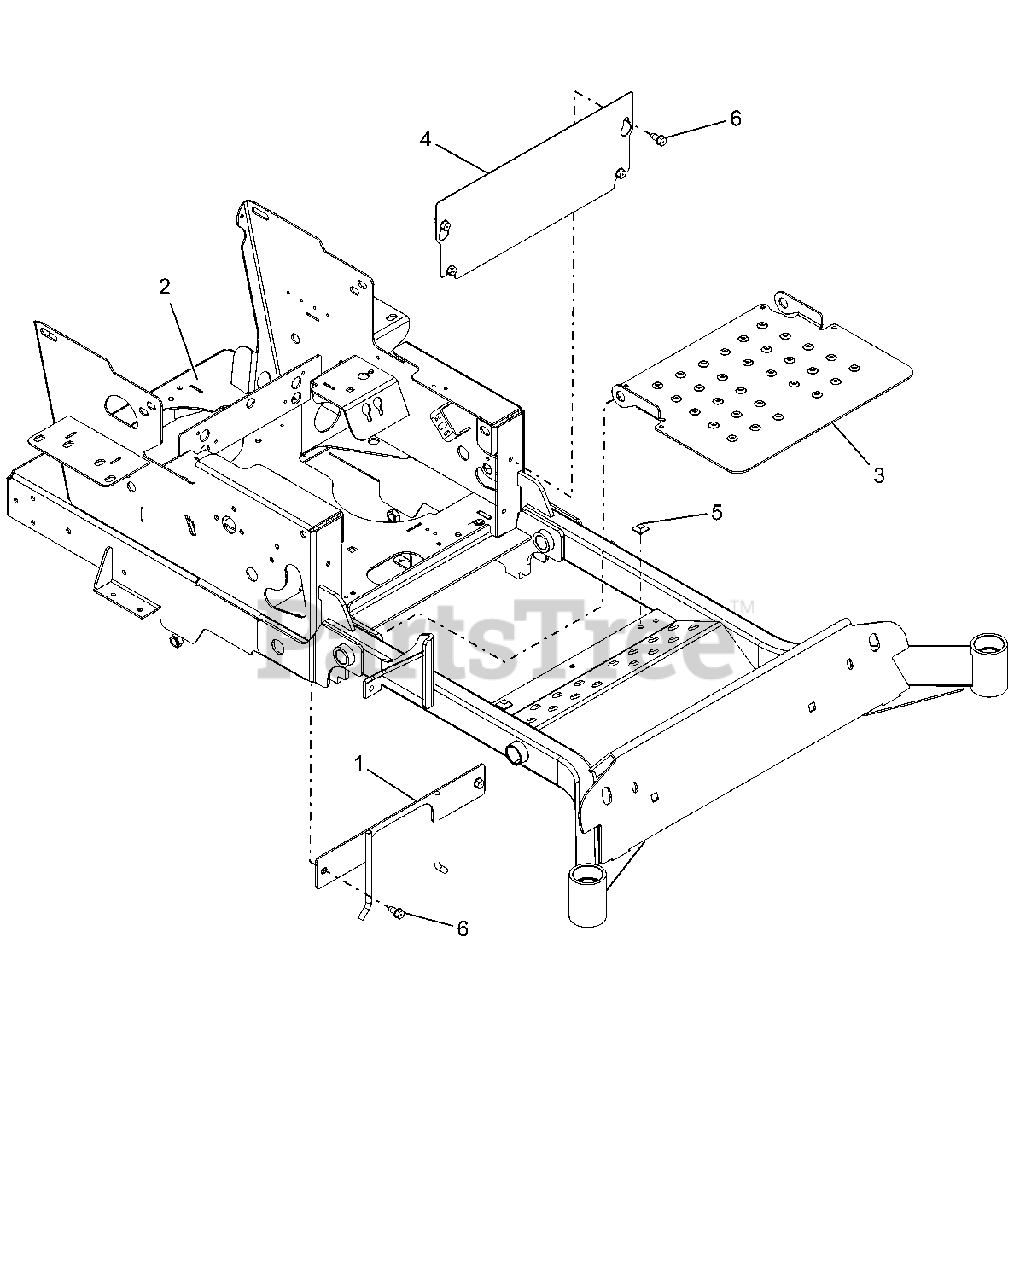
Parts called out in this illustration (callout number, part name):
1	WLDMT, PTO BELT FINGER-BLACK
2	WLDMT, 52"-60" HD FRAME (BLACK)
3	PANEL, INSPECTION
4	PLATE, KICK (RED)
6	SCR-TAP .38-16X.75 HWH TR YWZ
